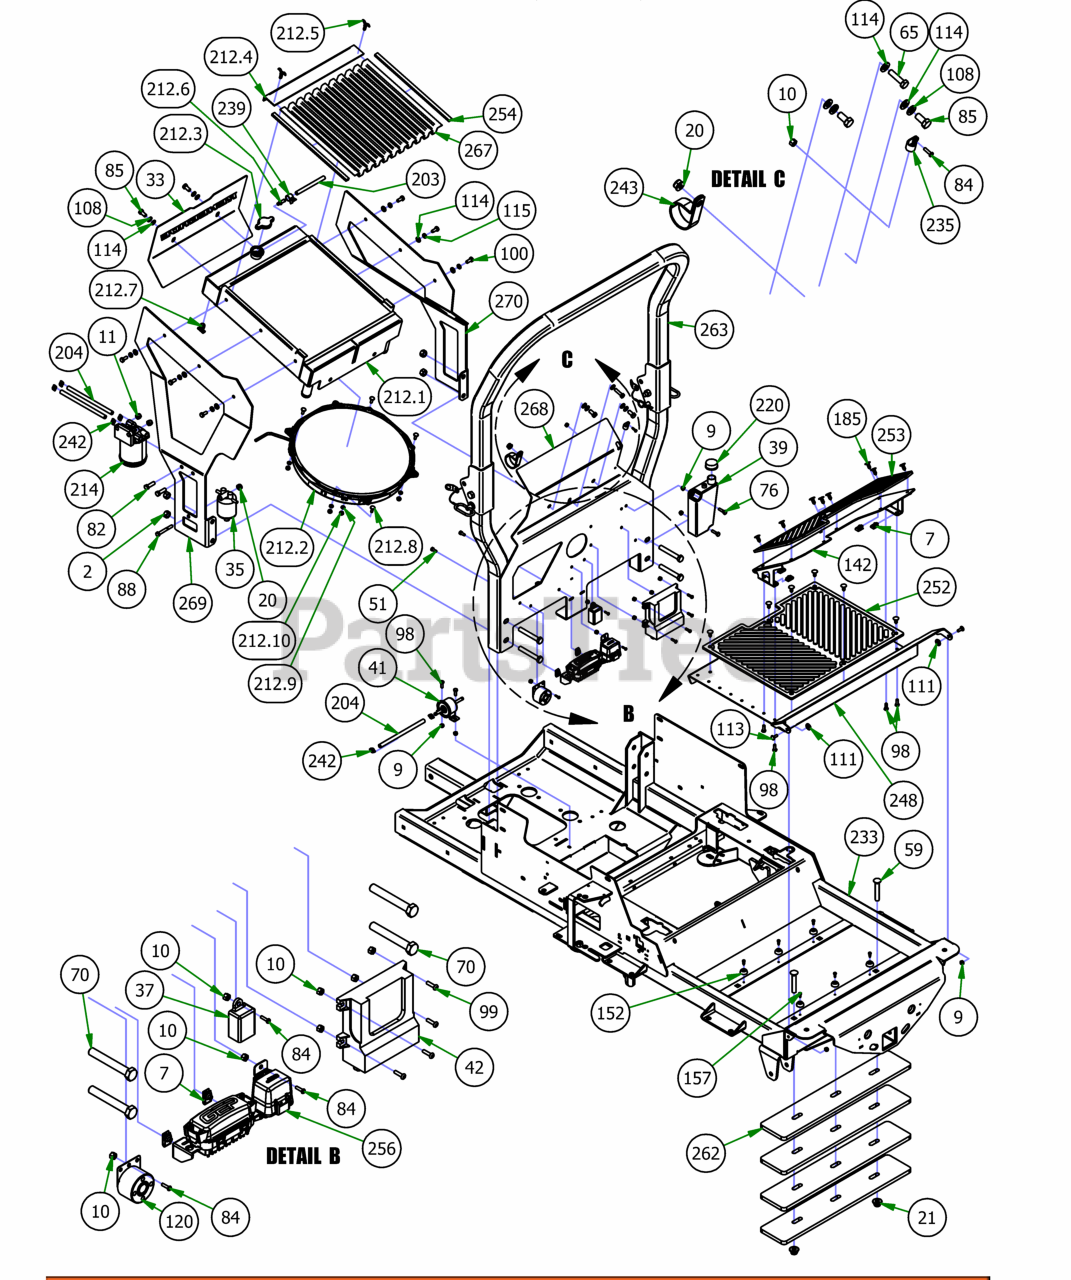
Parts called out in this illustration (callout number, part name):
2	1/2" Center Lock Nut
7	1/4-20 Cage Nut
9	1/4-20 Hex flang lock nut
10	10-24 Nylon Insert Locknut
11	3/8 Nylock Nut
20	5/16-18 Nylon Flange Nut
21	1/2-13 NYLON INSERT FLANGE LOCKNUT ZINC
33	2019 Diesel Upper Rear Cover
35	Caterpillar Fuel Bowl Kit
37	Auto Shut Down for Cat Diesels
39	overflow Reservoir- 27Kaw & 28/35Hp Diesel
41	Electric Fuel Pump
42	ECM for 1100cc Diesel
51	M6-1.0 X 16MM Hex Bolt
59	1/2-13 x 3 Carriage Bolt Grade 5
65	5/16 x 1 1/4 Hex Bolt
70	1/2 x 3 1/2 Flange Bolt Grade 8
76	1/4-20 x 1 GR 5 hex bolt zinc
82	3/8" x 1 1/4" Hex Bolt
84	10-24 X 5/8 BS Button Head Bolt
85	3/8" x 3/4" Hex Bolt
88	5/16" x 2 1/2" Bolt
98	1/4" x 3/4" Hex Bolt
99	10-24 x 1 BS C/S 18-8 SS
100	5/16" x 3/4" Hex Bolt
108	3/8" Lock Washer
111	.360 ID Plastic Washer
113	1/4" x 3/4" Carriage Bolt
114	5/16" Flat Washer
115	5/16" Lock Washer
120	Heat Warning Piezo Buzzer
142	2019 Outlaw Adjustable Foot Plate
152	Button Bumper
157	#10 x 1/2" Self Tapping Screw
185	Ratchet Fastener
203	5/16 Clear Hose x 42"
204	5/16 Fuel Line Hose - Priced Per Foot
212	2019 Diesel Radiator Kit
212.1	2019 Diesel Radiator
212.2	Electric Fan for 2019 Diesel Radiator
212.3	radiator cap
212.4	Screen Rentention Plate for 2019 Diesel Radiator
212.5	1/4-20 x 3/4 Thumb Screw
212.6	1/4 Barb to 3/16 NPT Overflow Fitting
212.7	1/4 NPT Drain Plug
212.8	1/4" x 3/4" Carriage Bolt
212.9	1/4" Lock Washer
212.10	1/4-20 Hex Nut
214	Fuel Filter
220	Reservoir Tank Cap-Overflow
233	2019 Renegade Diesel Frame - Powdercoated
235	3/8 Cable Clamp-Black Nylon
239	5/8 Hose Clamp
242	2 EAR CLAMP 12.5mm-15mm
243	Diesel Clamp 1 3/4" Vinyl
248	2019 Outlaw Floorboard
252	OUTLAW2019_FLOORMAT
253	FLOORMAT_OUTLAW_2019
254	Rubber Trim
256	2019 24.7 Diesel Harness
262	2019 Outlaw Counter Weight
263	2019 2X2 Folding ROPS
267	Radiator Screen - Diesel
268	2019 Diesel Radiator Mount - Front
269	2019 Diesel Radiator Mount - Right
270	2019 Diesel Radiator Mount - Left
